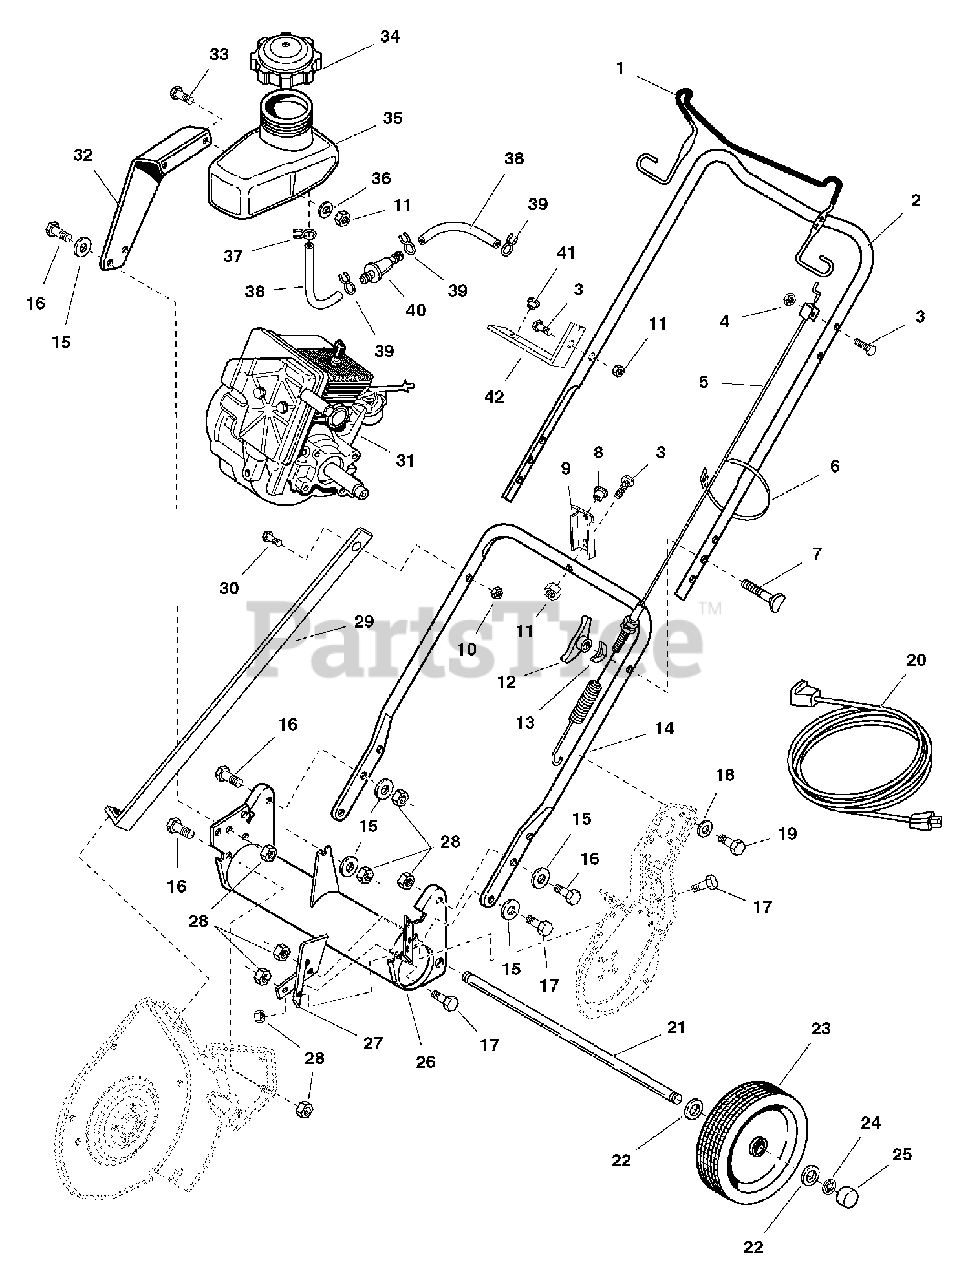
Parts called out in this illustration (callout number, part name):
1	HANDLE, Auger Control
2	HANDLE, Upper
3	CAPSCREW, Hex Hd., 1/4-20 x 1-1/4
4	NUT,Hex Centerlock, 1/4-20
5	CABLE, Auger Control
6	TIE, Self Locking
7	BOLT, Rd. Hd., 5/16-18 x 1-3/4
8	SNAP BUSHING, 3/8
9	BRACKET, Chute Rotator Rod
10	NUT, Hex Lk., #10-24
11	NUT, Hex Lk. Esna, 1/4-20
12	KNOB, Wing
13	WASHER, Curved, 5/16
14	HANDLE, Lower
15	WASHER, 3/4
16	CAPSCREW, Hex Hd., 5/16-18 x 3/4
17	CAPSCREW, Hex Hd., 5/16-18 x 1
18	LOCKWASHER, 5/16
19	CAPSCREW, Hex Hd., 5/16-18 x 3/4
20	CORD,Extension (Electric Start Models)
21	SHAFT, Axle
22	WASHER
23	TIRE, Semi-pneumatic
24	RING, Retainer, Ext., #37
25	CAP,Hub
26	FRAME ASSY.
27	BRACKET, Reinforcement
28	NUT, Hex Lk.,Esna, 5/16-18
29	STRAP, Support
30	SCREW, Hex Wshr. Hd., #10-24 x 1-1/4
31	ENGINE, Manual Start
31	ENGINE, Electric Start
32	BRACKET, Fuel
33	CAPSCREW, Hex Hd., 1/4-20 x 3/4
35	TANK, Fuel
36	WASHER
37	CLAMP, Hose
38	HOSE, Fuel, 5-1/2 long
39	CLAMP, Wire Form
40	FILTER, Gas
41	SNAP BUSHING, 1/4
42	BRACKET, Starter Handle
